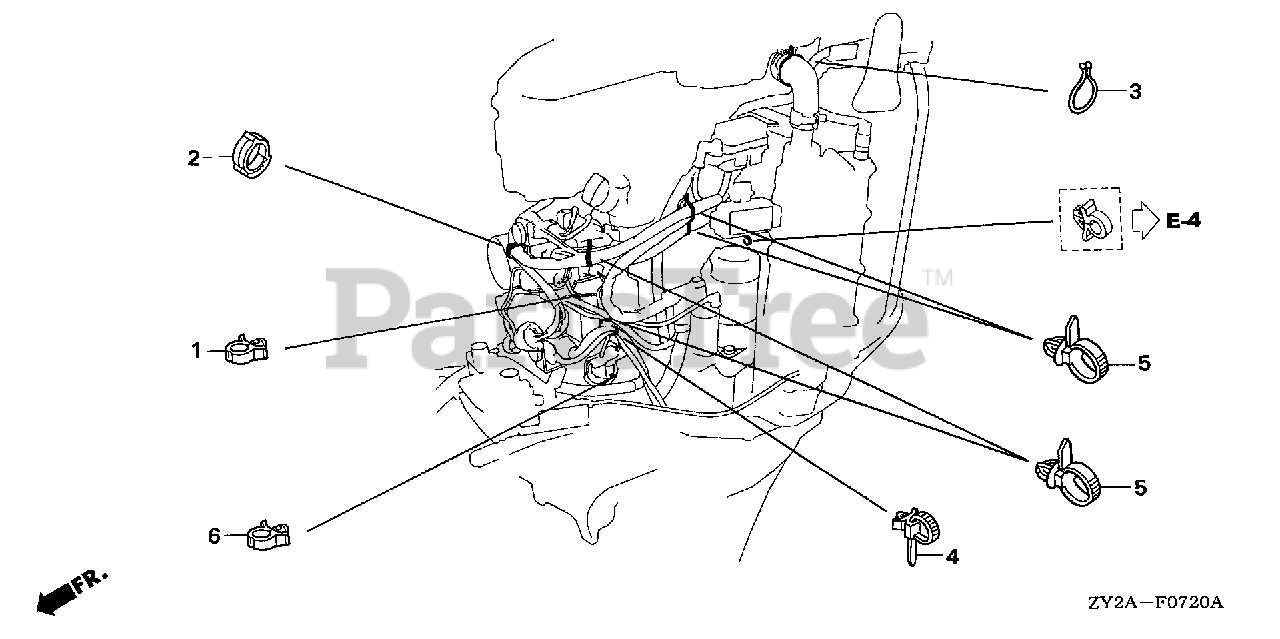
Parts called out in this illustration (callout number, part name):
1	CLIP, BRAKE PIPE (A) (FOR STT MAG. CORD)
2	TIE, CABLE
3	CLIP B, HARNESS
4	STRAP, CABLE (118MM) (BLACK)
5	CLIP, HARNESS BAND (145MM) (BLACK)
6	CLIP, BRAKE PIPE (A) (FOR NEUTRAL SWITCH)
